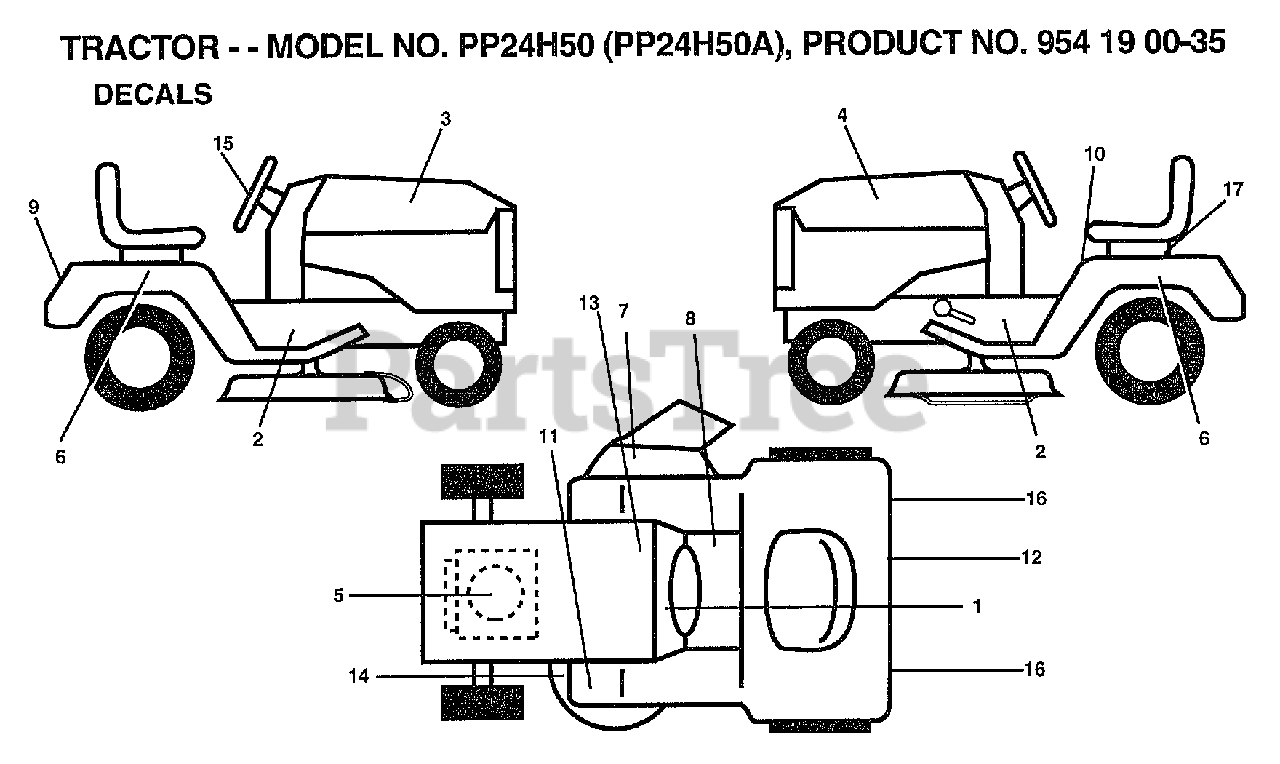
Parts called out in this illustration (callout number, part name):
1	DECAL OPER INSTR.
2	"DECAL.CHASSIS.50"""
3	DECAL.HOOD.RH
4	DECAL.HD.LH
6	DECAL.FENDR.AUTO
7	"DECAL, WARNING"
8	DECAL BRAK PARK
9	DECAL.FENDER.BELT.GUARD
10	DECAL.CAUT.ENG/FR
11	DECAL T
12	DECAL D-BAR CNTRL
13	DECAL.BATRY.3-3908
15	DECAL INS STRG WH
16	REFLECTOR-TAIL YT
17	RETAINER-SPRING
